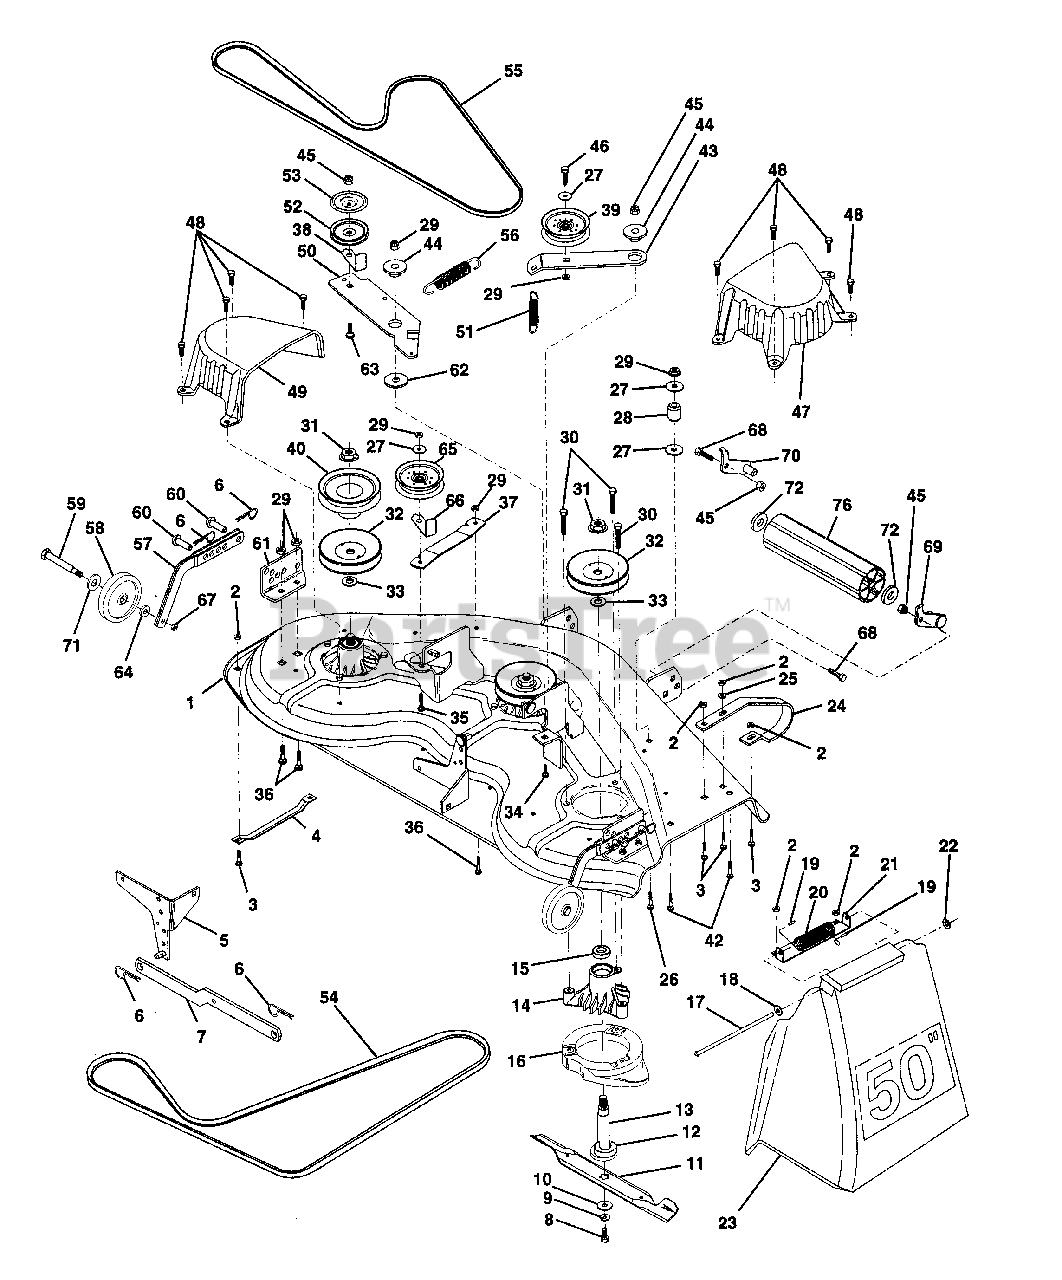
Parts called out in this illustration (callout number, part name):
1	Deck Asm., Mower 50" Vented
2	Locknut, Hex W/Ins 5/16-18 Unc
3	Bolt, Carriage 5/16-18 x 3/4
4	Runner, Mower LH
5	Bracket Asm., Sway Bar
6	Retainer, Spring
7	Arm Suspension, Rear
8	Bolt 3/8-24 x 1.25 Gr. 8 Patched
9	Washer, Lock Hvy 3/8 Unplated
10	Washer, Hard Blade Mower Vented
11	Blade
12	Bearing, Ball #6204 (Mandrel)
13	Shaft Asm., W/Lower Brg
14	Housing, Mandrel 50" Vent
15	Bearing, Ball Mandrel
16	Stripper, Mower Vented
17	Rod, Hinge
18	Washer 11/32 x 5/8 x 16 Ga.
19	Cap, Sleeve
20	Spring, Torsion Deflector
21	Bracket, Deflector
23	Shield, Deflector Mower
24	Runner, RH
25	Washer 11/32 x 3/4 x 16 Ga.
26	Bolt, Carriage 3/8-16 x 1-3/4 Gr. 5
27	Washer 13/32 x 13/16 x 16 Ga.
28	Spacer, Spring Stop Idler
29	Nut, Lock Hex W/Wsh 3/8-16 Unc
30	Screw Thdrol Hex Head
31	Nut, Flg Top Lock Cntr 9/16
32	Pulley, Mandrel
33	Washer, Spacer Mower Vented
34	Bolt, Carriage 3/8-16 x 1-1/4
35	Bolt, Carriage 3/8-16 x 2
36	Bolt, Carriage 3/8-16 x 1 Gr. 5
37	Stiffener, Arm Idler
38	Keeper, Belt Idler
39	Pulley, Idler Flat
40	Pulley, Driven
42	Bolt, Carriage 5/16-18 Unc x 3/4
43	Arm, Idler Secondary
44	Spacer, Retainer
45	Nut, Crownlock 3/8-16 Unc
46	Bolt, Fin Hex 3/8-16 Unc x 1-3/4
47	Cover, Mandrel RH
48	Screw, Thd Roll 1/4-20 x 5/8
49	Cover, Mandrel LH
50	Arm, Idler Primary
51	Spring, Secondary
52	Pulley, Idler V Groove
53	Shield, Idler
54	V-Belt, Mower Primary
55	V-Belt, Mower Secondary
56	Spring, Primary
57	Bar Asm., Wheel Gauge
58	Wheel, Gauge
59	Bolt, Shoulder
60	Pin, Clevis
61	Bracket, Wheel Gauge
62	Washer Hardened
63	Bolt Carriage 3/8-16 x 1-1/2
64	Washer 3/8 x 7/8 x 14 Ga.
65	Pulley Idler Flat Mower
66	Keeper, Belt Idler 50" Vent
67	Nut, Center Lock 3/8-16
68	Bolt, Fin Hex 3/8-16 x 1
69	Bracket, Asm. Noseroller RH
70	Bracket, Asm. Noseroller LH
71	Washer 17/32 x 15/16 x 12 Ga.
72	Washer 17/32 x 7/8 x 16 Ga.
76	Roller, Nose
